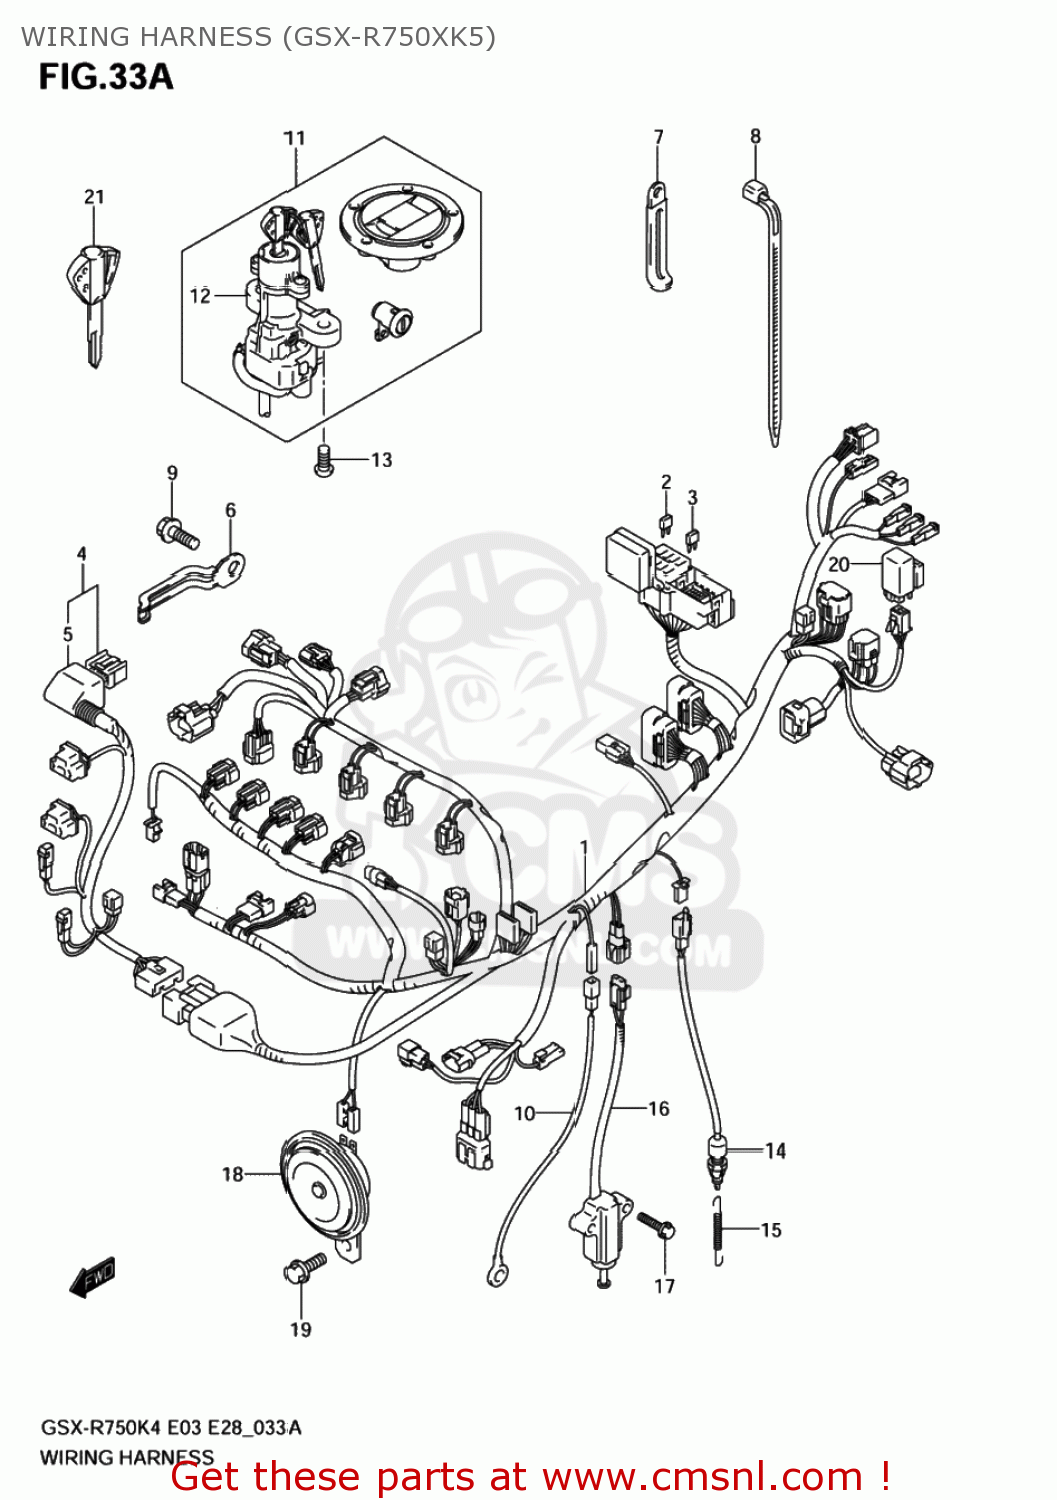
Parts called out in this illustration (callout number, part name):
1	HARNESS,WIRING NO.1
2	FUSE(10A)
3	FUSE(15A)
4	HARNESS,WIRING NO.2
5	COVER,SPEEDOMETER COUPLER
6	CLAMP
7	CLAMP(L:45)
8	CLAMP(L:125)
9	BOLT
10	WIRE,OIL PRESSURE SWITCH LEAD
11	LOCK SET
12	LOCK ASSY,STEERING
13	BOLT(8X20)
14	SWITCH ASSY,STOP LAMP
15	SPRING
16	SWITCH ASSY,SIDE STAND
17	BOLT
18	HORN ASSY
19	BOLT
20	RELAY ASSY
21	KEY,BLANK
